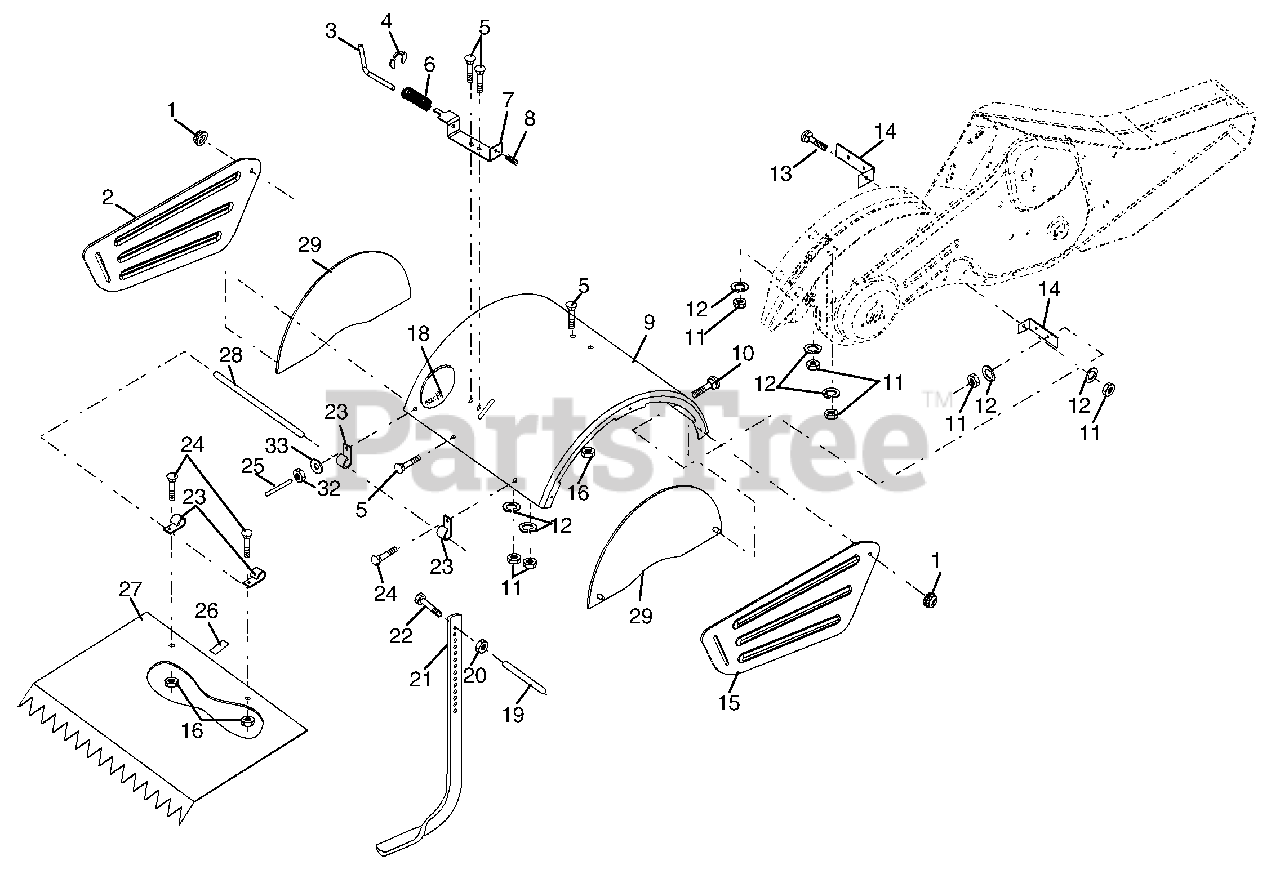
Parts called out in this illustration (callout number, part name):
1	Nut, Flange 5/16-18
2	Shield, Side, Outer L. H.
3	Pin, Stake, Depth
4	Ring, Klip
5	Bolt, Carriage 5/16-18 x 3/4
6	Spring
7	Bracket, Latch
8	Spring, Depth Stake
9	Shield, Tine
10	Bolt 5/16-18 x 1
11	Nut, Hex 5/16-18
12	Washer, Lock 5/16
13	Bolt, Carriage 5/16-18 x 1-1/4
14	Bracket, Shield Tine
15	Shield, Side, Outer R.H.
16	Nut, Hex Flange 1/4-20 Unc
18	Bolt, Carriage 1/4-20 x 1-1/4 Gr. 5
19	Grip
20	Nut, Hex 3/8-16
21	Stake, Depth
22	Bolt, Hex 3/8-16 x 2
23	Hinge
24	Bolt, Carriage 1/4-20 x 1/2 Gr. 5
25	Cap, Vinyl
26	Pad, Idler
27	Shield, Leveling
28	Pin, Hinge
29	Shield, Side
32	Nut Fin Hex 1/4-20 Unc
33	Washer Lock Hvy Helical 1/4
